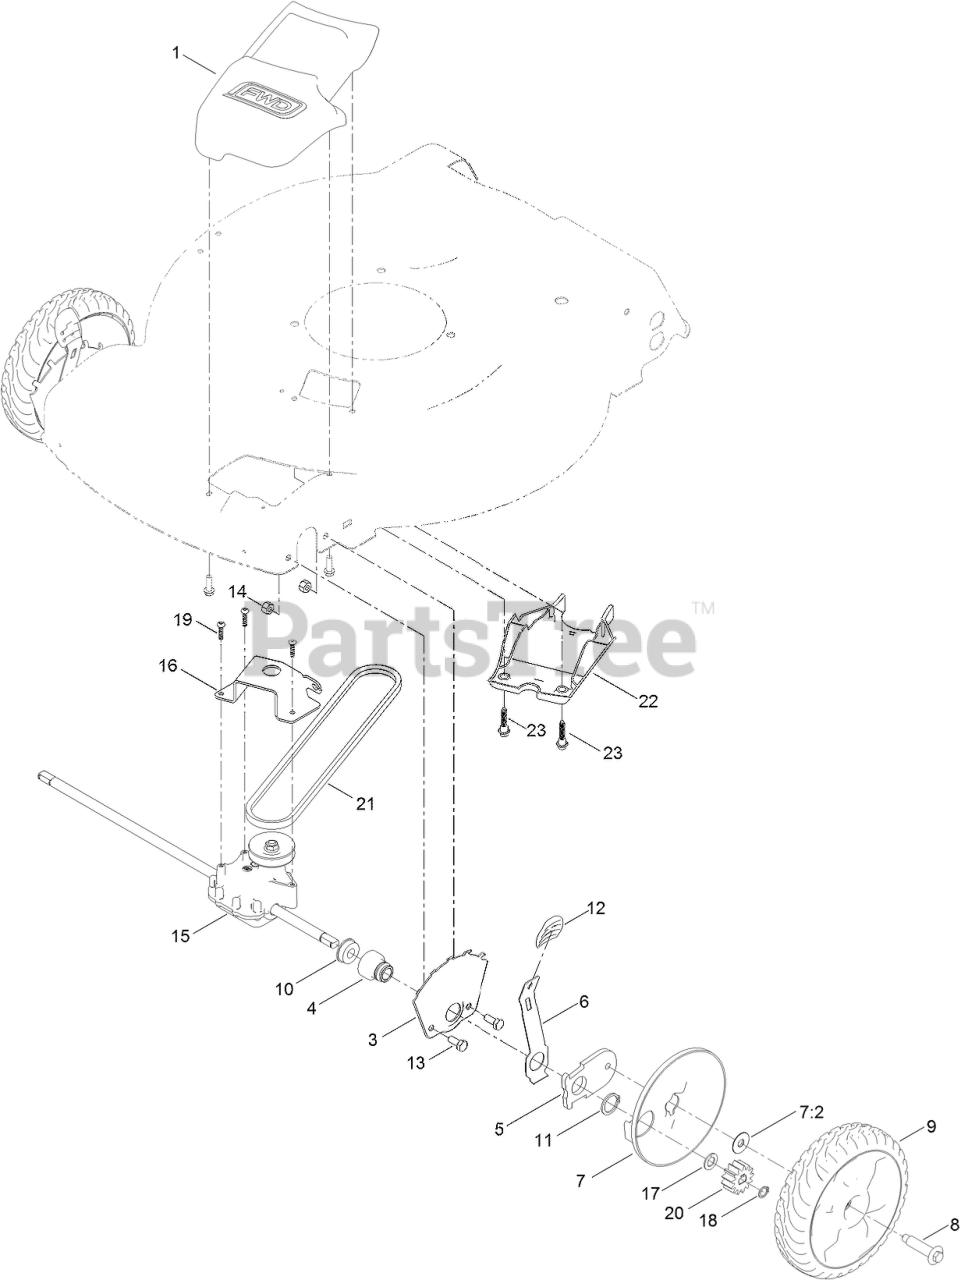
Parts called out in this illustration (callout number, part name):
1	COVER-BELT
3	PLATE-HOC, FRONT
4	RETAINER-BEARING, HOC
5	ARM-PIVOT, FRONT
6	ARM-SPRING
7	WHEEL COVER ASM
7:2	WASHER-STEPPED
8	BOLT-SHOULDER
9	8 IN WHEEL ASM
10	BEARING-BALL
11	RING-RETAINING
12	KNOB-LEVER, HOC
13	SCREW-HH
14	NUT-HEX
15	TRANSMISSION
16	BRACKET-TRANSMISSION
17	WASHER-THRUST
18	RING-RETAINING
19	SCREW-PLASTITE
20	GEAR-PINION, 13T
21	V-BELT
22	COVER-BELT, FRONT (LOWER)
23	SCREW-SHOULDER, HHF
